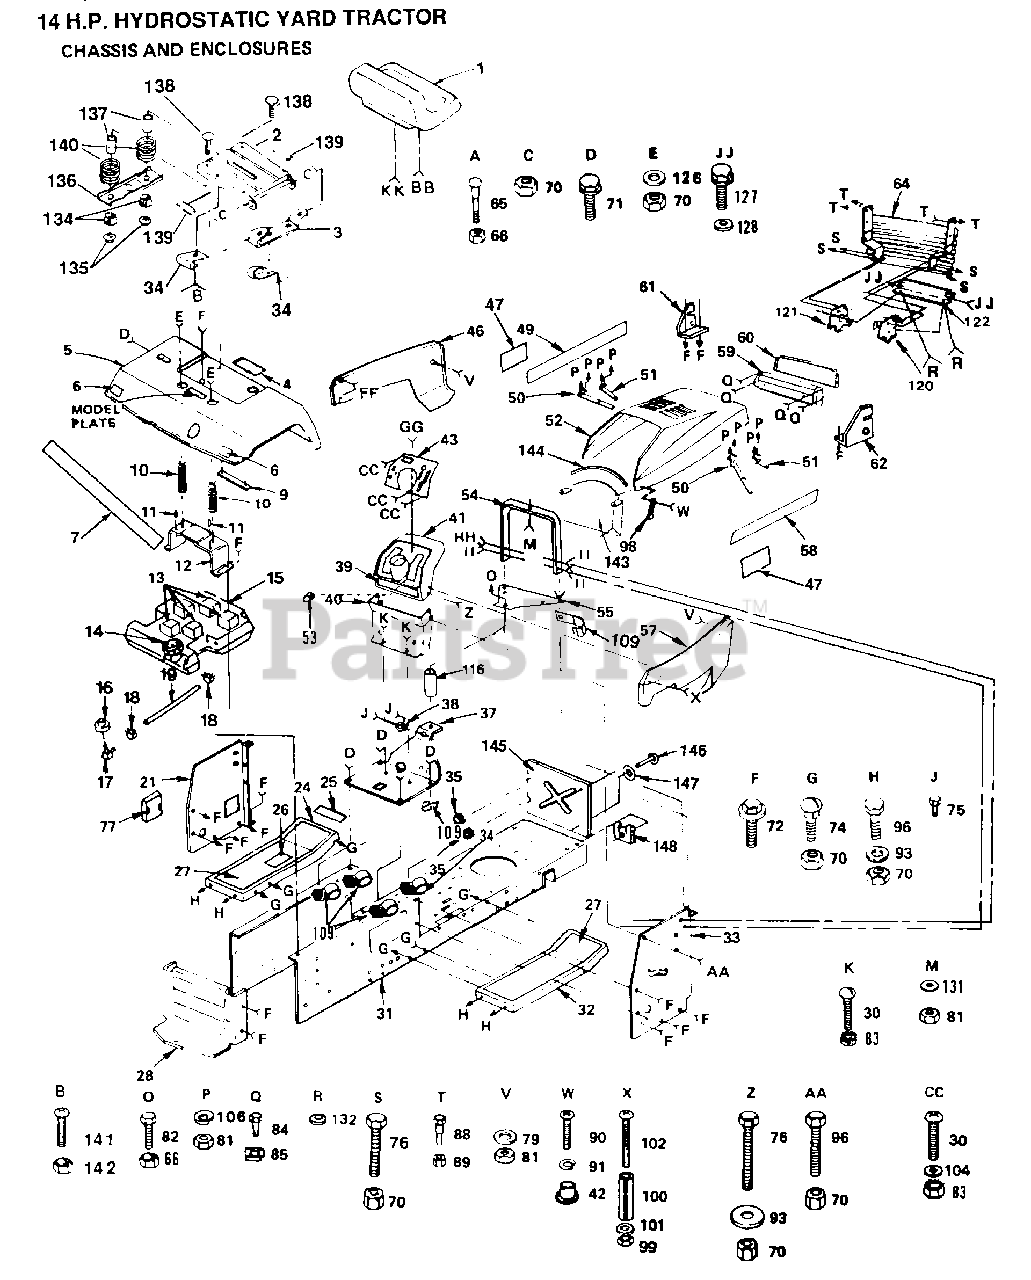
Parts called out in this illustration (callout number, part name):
4	DECAL
6	REFLECTOR-TAIL YT
10	SPRING COMPRESSIO
12	BRKT FENDER T
13	PAD-SPACER T
16	BUSHING OUTLET T
17	FUEL TANK STEM GT
18	HOSE CLAMP
21	PANEL DASH LH
25	DECAL T
26	DECAL DRIVE BELT
27	PAD FOOTREST T
30	SCREW
31	CHASSIS ASSY
37	SADDLE
40	LOWER DASH
42	WELDNUT
49	DECAL HOOD LH
53	PLUG BUTTON T
60	LENS LT
61	SUPPORT RH YTH
62	SUPPORT LH YTH
71	SCREW LT
72	SCREW
74	BOLT
76	BOLT
77	COVER ACCESS
79	WASHER PM
82	BOLT
85	"""J"" FASTENER LT"
90	SCREW
91	LOCKWASHER
93	WASHER
98	HOOD LATCH T
100	SPACER LT
101	WASHER
102	SCREW
104	WASHER
109	CLIP T
116	SPACER
120	SUPPORT LH YTH
121	SUPPORT RH YTH
126	WASHER
127	SCREW
128	WASHER PM
132	WASHER
134	BUSHING
136	BRKT SWITCH
137	SPACER SPLIT
138	BOLT
142	"NUT,KEPS"
143	VERTICAL BAFFLE
144	FOAM STRIP T
146	STUD.1/4.TURN
147	RECEPTACLE LT
148	RETAINER LT
